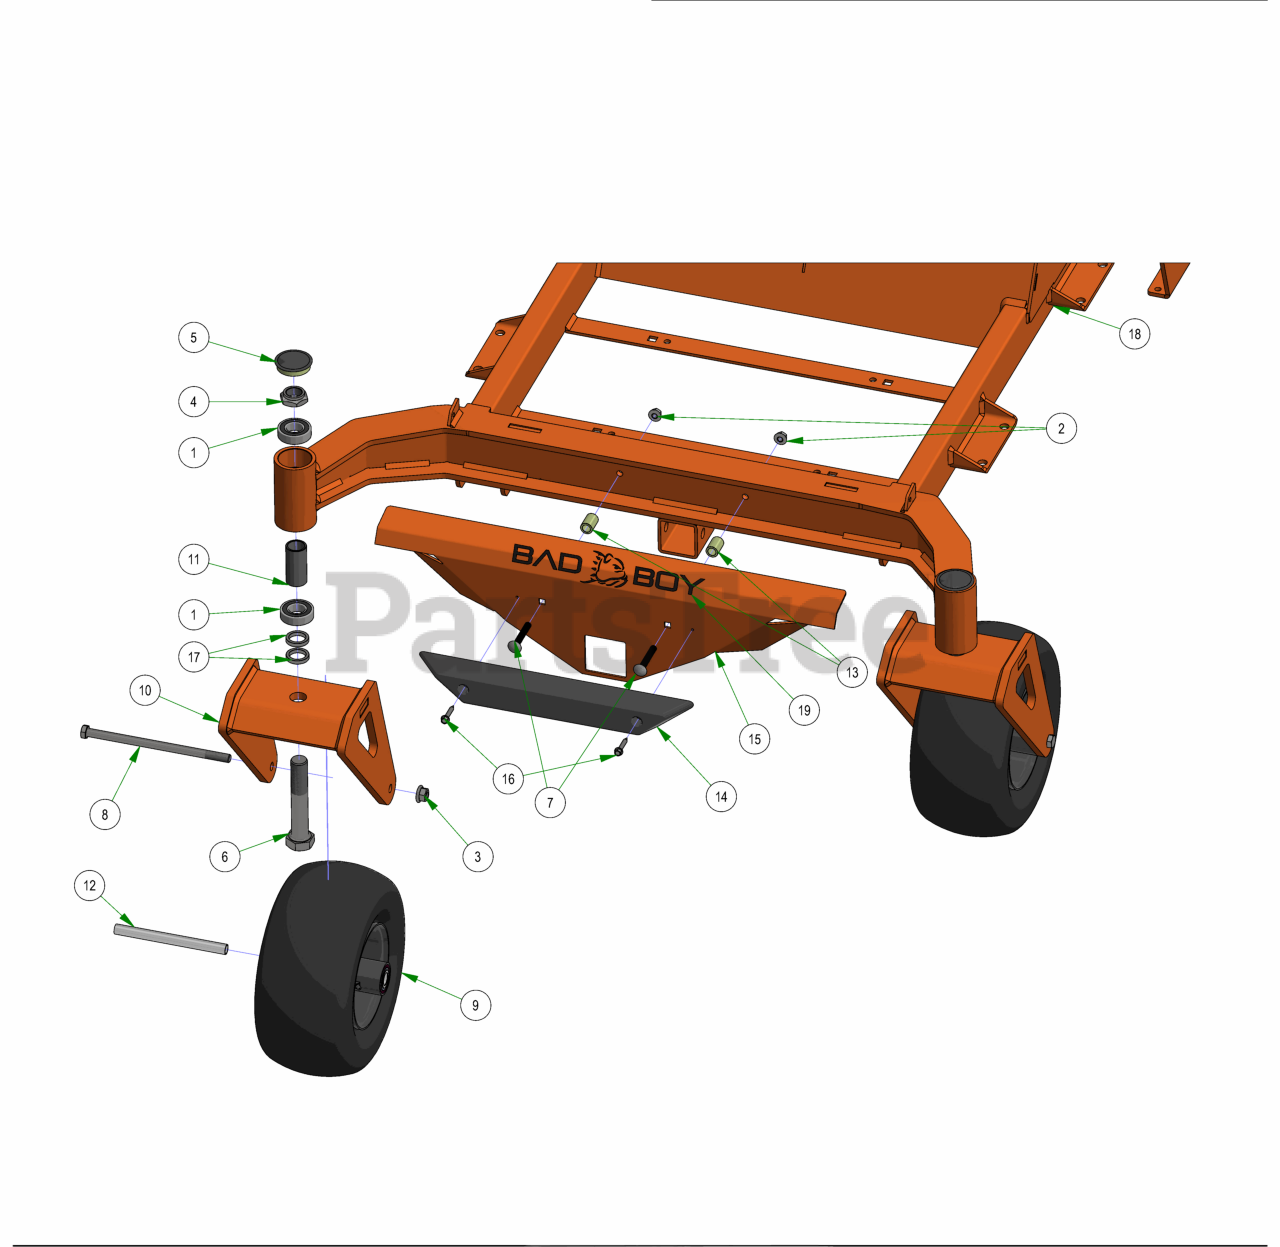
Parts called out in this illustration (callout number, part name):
1	1641 BEARING W/2 CONTACT RUBBER SEALS
2	3/8-16 NYLON INSERT FLANGE LOCKNUT (GR.F) ZINC
3	1/2-13 NYLON INSERT FLANGE LOCKNUT ZINC
4	1"-14 NYLON INSERT JAM LOCKNUT ZINC
5	2017 Bearing Cover
6	1"-14 X 5-1/2 HEX CAP SCREW (GR.8) ZINC YELLOW
7	3/8" x 2 1/2" Carriage Bolt
8	1/2-13 X 9 HEX CAP SCREW (GR.5) ZINC
9	13x6.50-6 Black No Flat Assembly
10	2019 Rebel Front Fork - Weldment - Black
11	2016 Front Bearing Spacer
12	Front Wheel Spanner
14	2017 XP BUMPER
15	2024 Rebel Front Bumper Plate
16	1/4-14 X 1-1/2 HEX WASHER UNSLOT TEK/3 ZINC
17	1.02 ID X 1.38 OD X .250 THK SPACER ZINC
18	2023 Rebel Frame - Painted
19	Flying Bulldog Front Bumper Decal
